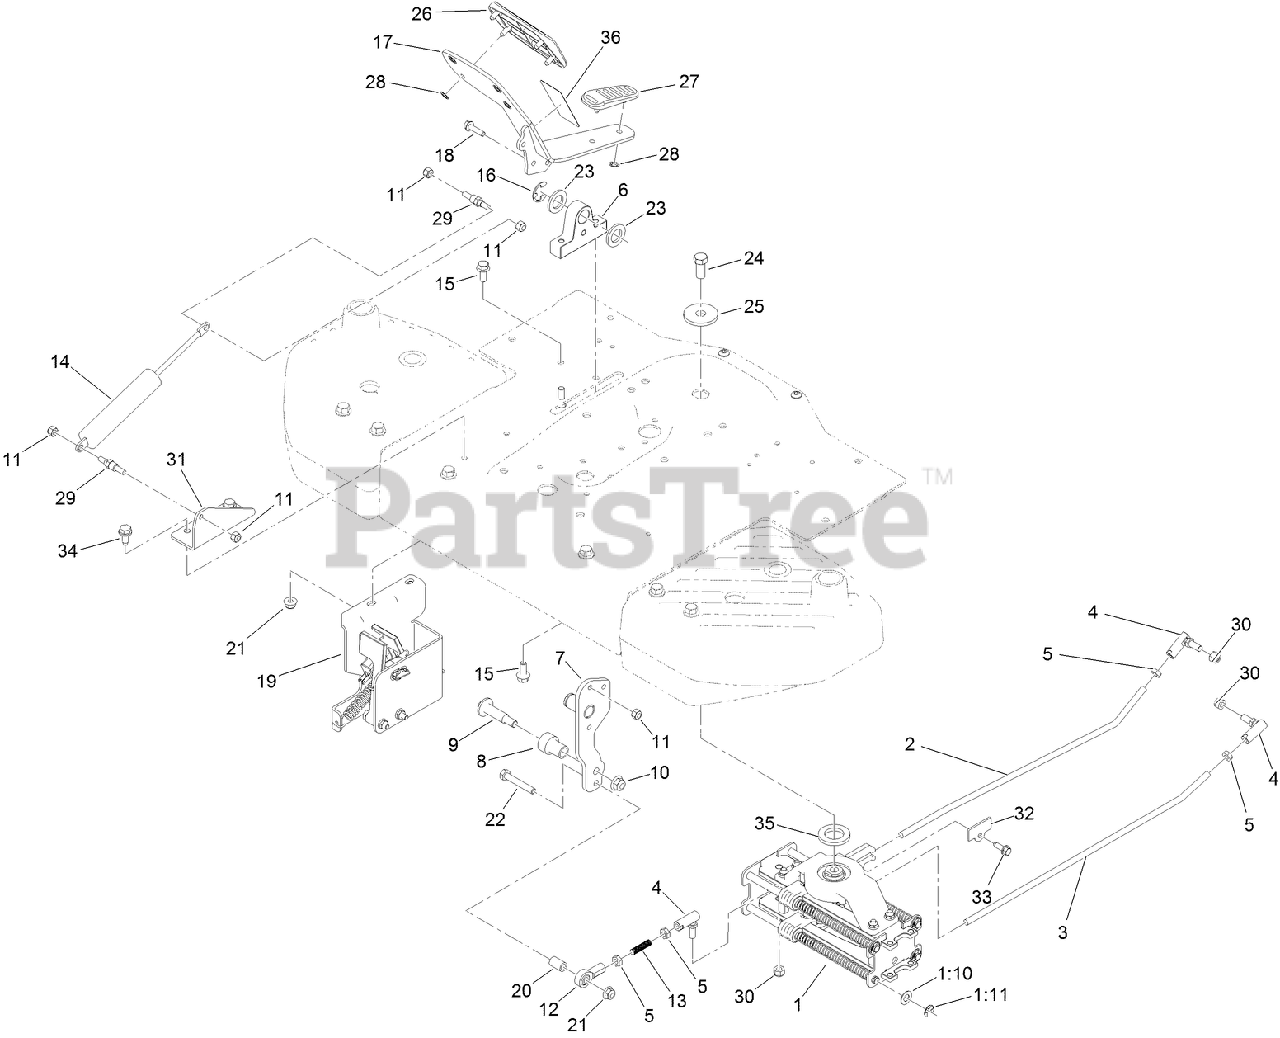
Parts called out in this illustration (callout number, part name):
1	SPEED CONTROL ASM
1:10	WASHER-THRUST
1:11	E-RING
2	ROD-HYDRO, RH
3	ROD-HYDRO, LH
4	BALLJOINT-RH (W/GROMMET)
5	NUT-JAM
6	MOUNT-PEDAL PIVOT
7	PIVOT LEVER ASM
8	ROLLER
10	NUT-HF, NI
11	NUT-LOCK, NI
12	BALLJOINT-RH
13	ROD-THREADED
14	DAMPER-NON CAVITATING
15	SCREW-HHF
16	E-RING
17	PEDAL-TRACTION
18	SCREW-HHF
19	NEUTRAL RETURN ASM
20	SPACER
21	NUT-HF, NI
22	SCREW-HH
23	WASHER
24	SCREW-HH
25	WASHER-THRUST
26	PAD-TOE, HYDRO PEDAL
27	PAD-HEEL, HYDRO PEDAL
28	NUT-PUSH
29	STUD-DAMPER
30	NUT-LOCK
31	BRACKET-DAMPER
32	COVER-END ROD
33	SCREW-HWH, THREAD ROLL
34	SCREW-HWHTF
35	SPACER-BEARING
36	DECAL-RELEASE, BREAK
